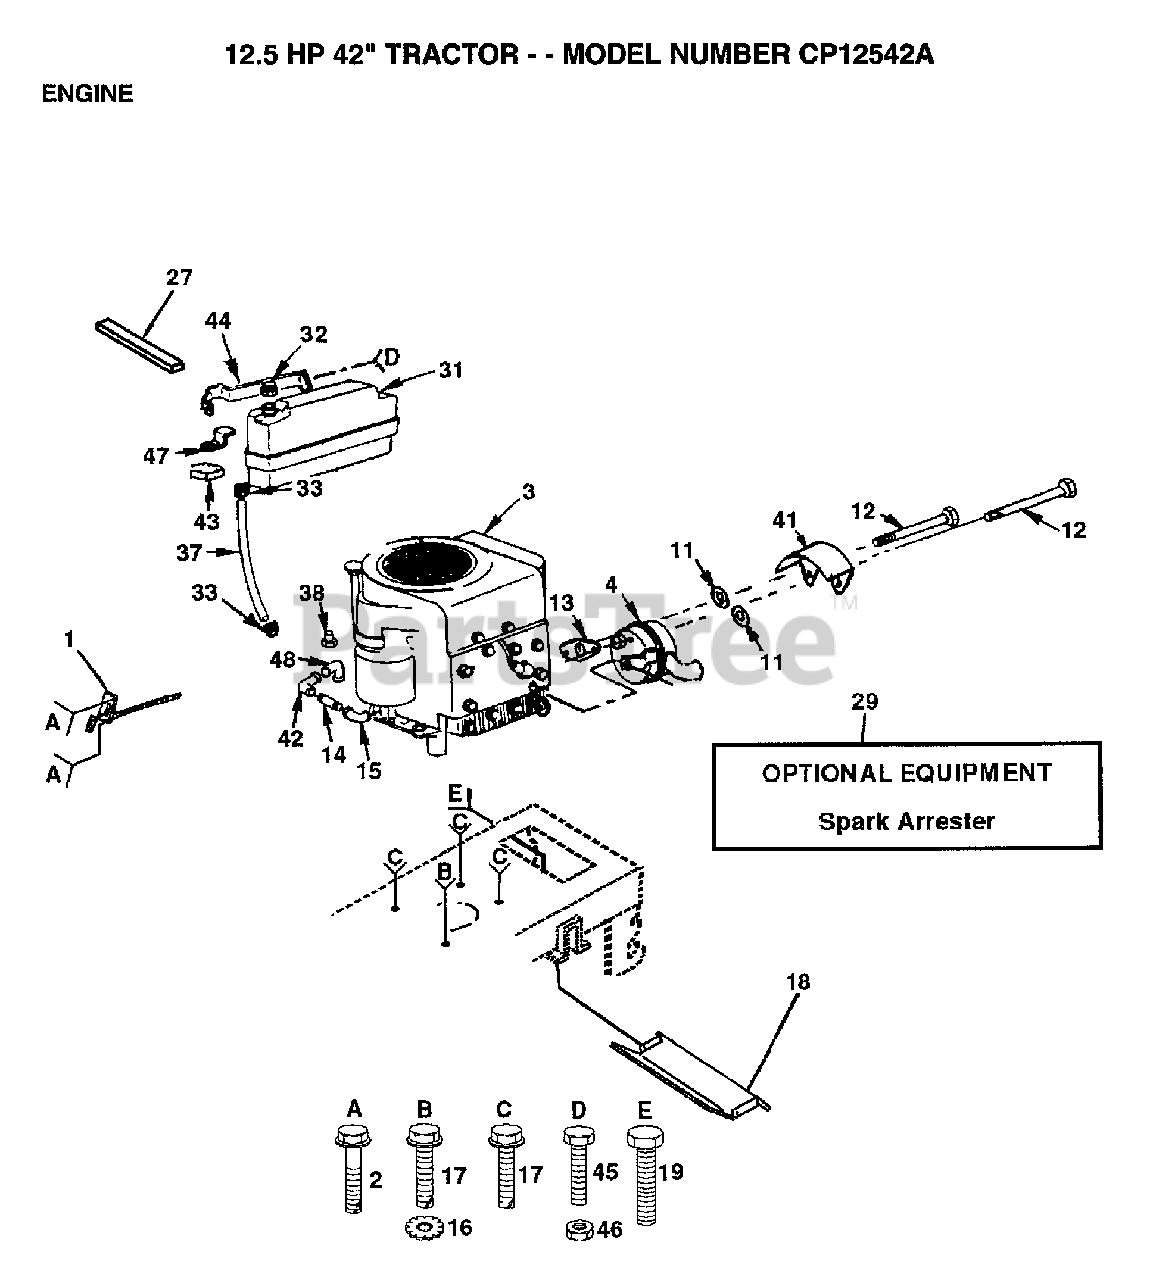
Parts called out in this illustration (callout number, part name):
2	SCREW LT
4	MUFFLER
12	BOLT
14	PIPE NIPPLE
15	STREET ELBOW LT
16	LOCKWASHER
17	SCREW
18	HEAT SHIELD
19	SCREW
31	FUEL TANK
33	HOSE CLAMP
37	HOSE T
41	HEAT SHIELD
42	STREET ELBOW LT
43	PAD-SPACER T
44	SUPT TANK FUEL
45	BOLT
47	BRACE-TANK LT
48	ELBOW
